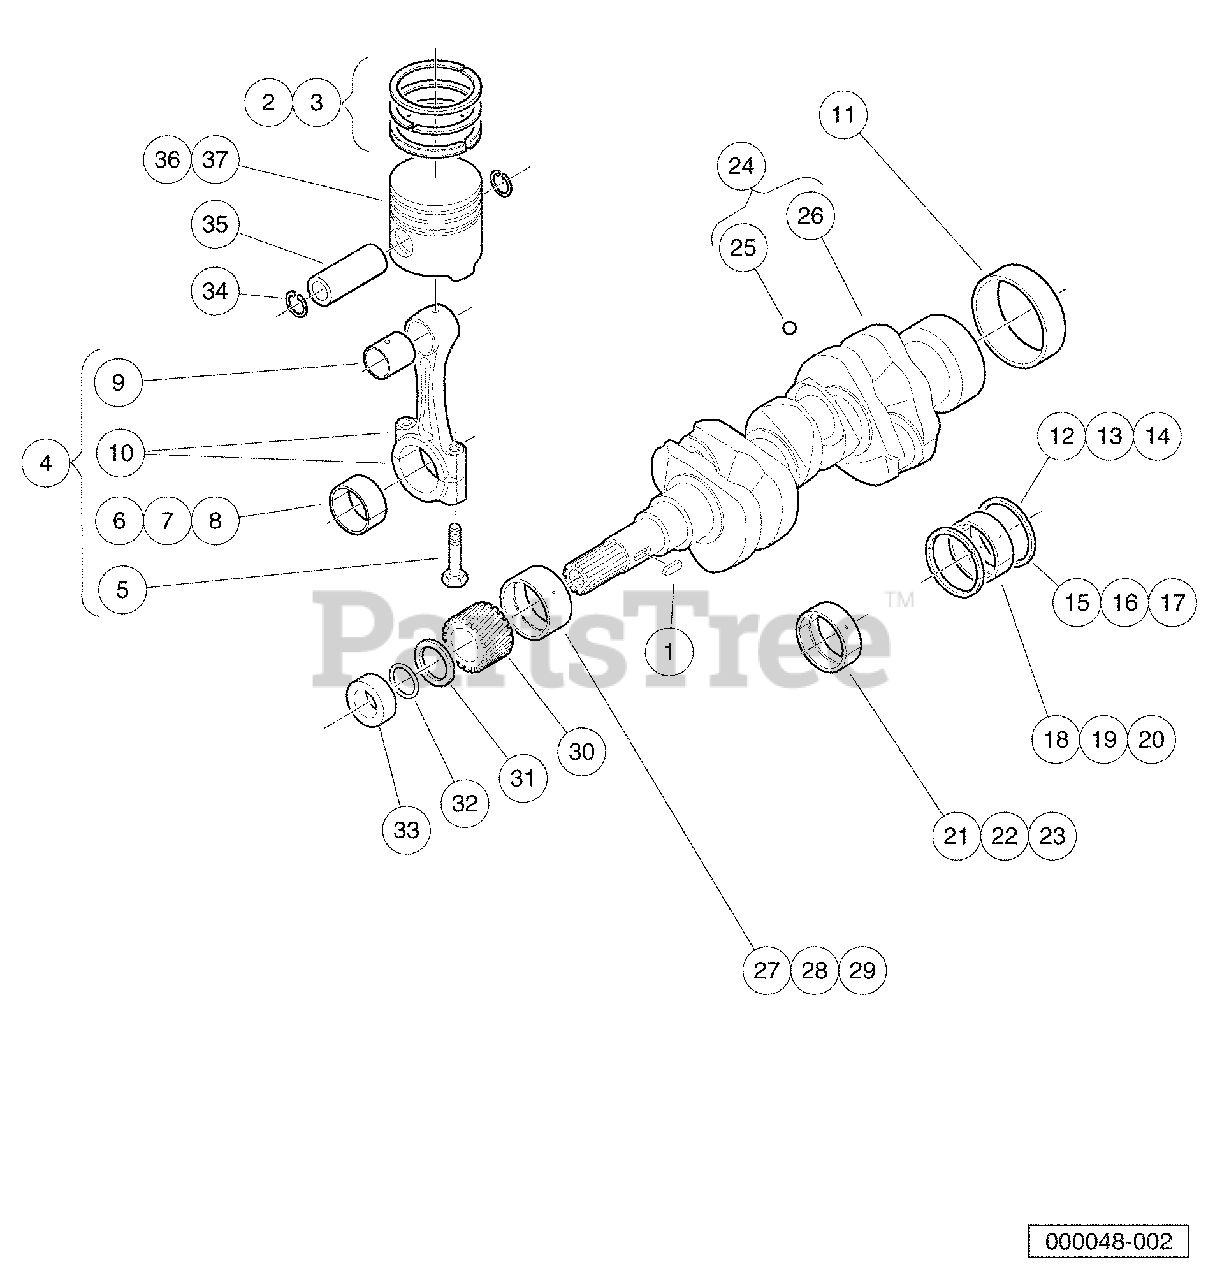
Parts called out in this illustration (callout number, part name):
1	Key, Feather, Short Camshaft
2	Assy Piston Ring, D722 Std
3	Assy Piston Ring, D722 +.025
4	Assy, Connecting Rod
5	Bolt, Connecting Rod
6	Metal, Crank, Rod, D722, Std
7	Metal, Crank, Rod, D722, .020
8	Metal, Crank, Rod, D722, .040
9	Bushing, Piston Pin, D722
10	Rod, Connecting
11	Sleeve, Crankshaft
12	Metal,crank, O Side, Std.
13	Metal,crank, O Side, +.020
14	Metal,crank, O Side, +.040
15	Metal,crank, I Side, Std
16	Metal,crank, I Side, +.020
17	Metal,crank, I Side, +.040
18	Metal, Crank, Main, Rear Std
19	Metal, Crank, Main, Rear -.020
20	Metal, Crank, Main, Rear -.040
21	Metal, Crank, Main, Mid Std
22	Metal, Crank, Main, Mid +.020
23	Metal, Crank, Main, Mid +.040
24	Crankshaft
25	Ball, Crankshaft.
26	Crankshaft.
27	Metal, Crank, D722, Frnt, Std
28	Metal, Crank, 722, Frnt, -.020
29	Metal, Crank, 722, Frnt, -.040
30	Gear, Crank
31	Slinger, Oil
32	O Ring, 23 X 26
33	Collar, Crankshaft
34	Circlip, Piston Pin
35	Pin, Piston
36	Piston, D722, Std
37	Piston, D722, +0.25
